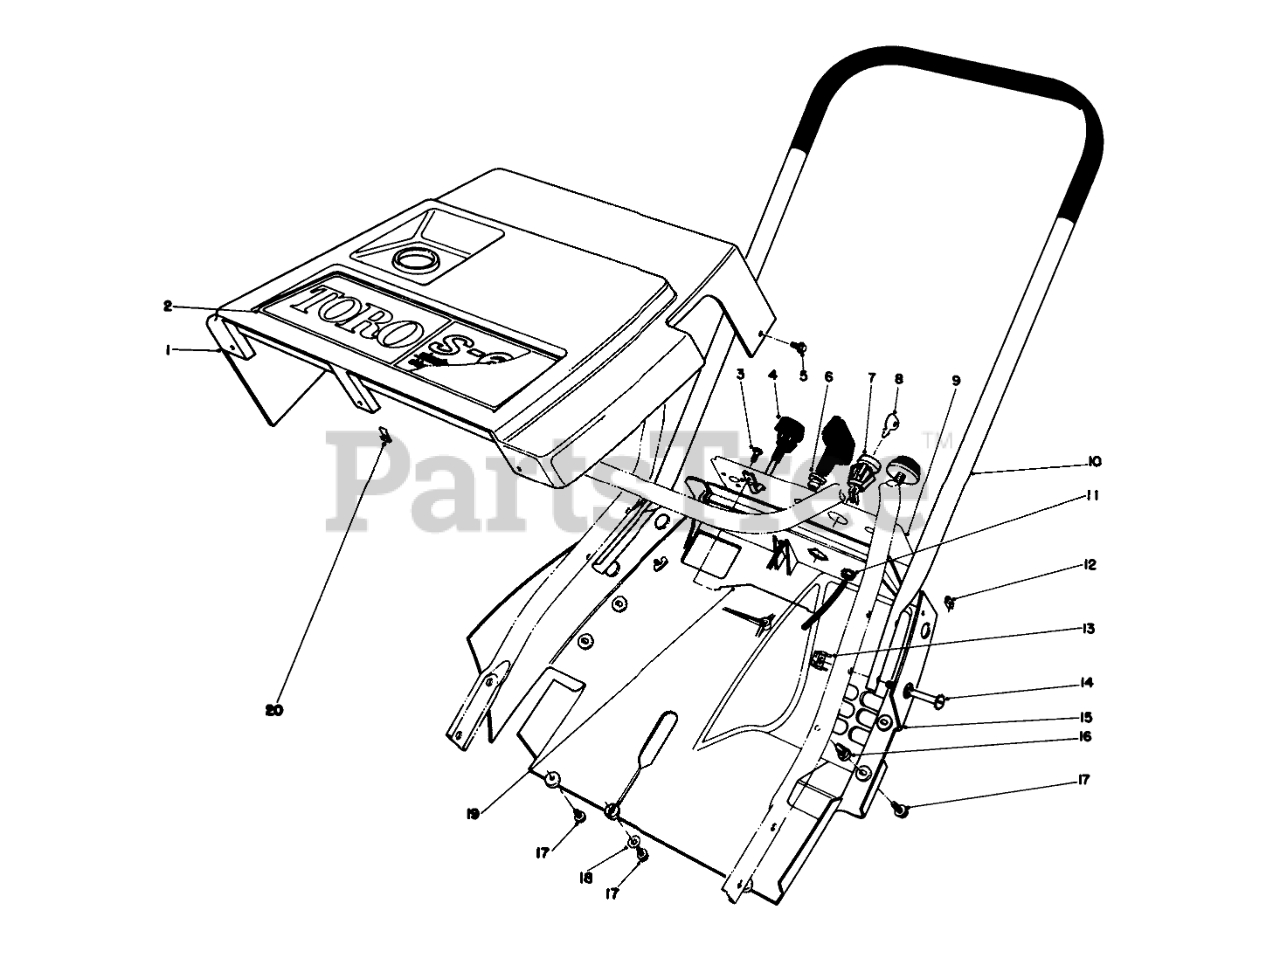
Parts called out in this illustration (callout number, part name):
1	Shroud-Upper
2	TORO DECAL
3	SCREW-PLASTITE
4	CHOKE CONTROL ASM
5	SCREW-HWHTF
6	GUIDE-ROPE, STARTER
7	SWITCH
8	Key
9	Decal-Control Panel
10	Handle-Upper
11	NUT-KEPS
13	TINNERMAN NUT
14	SCREW-HEX HD SLOT
15	LOWER SHROUD
16	Nut-Push
17	Self Tapping Screw
18	WASHER-FLAT
19	CONTROL WIRE
20	NUT "U"
